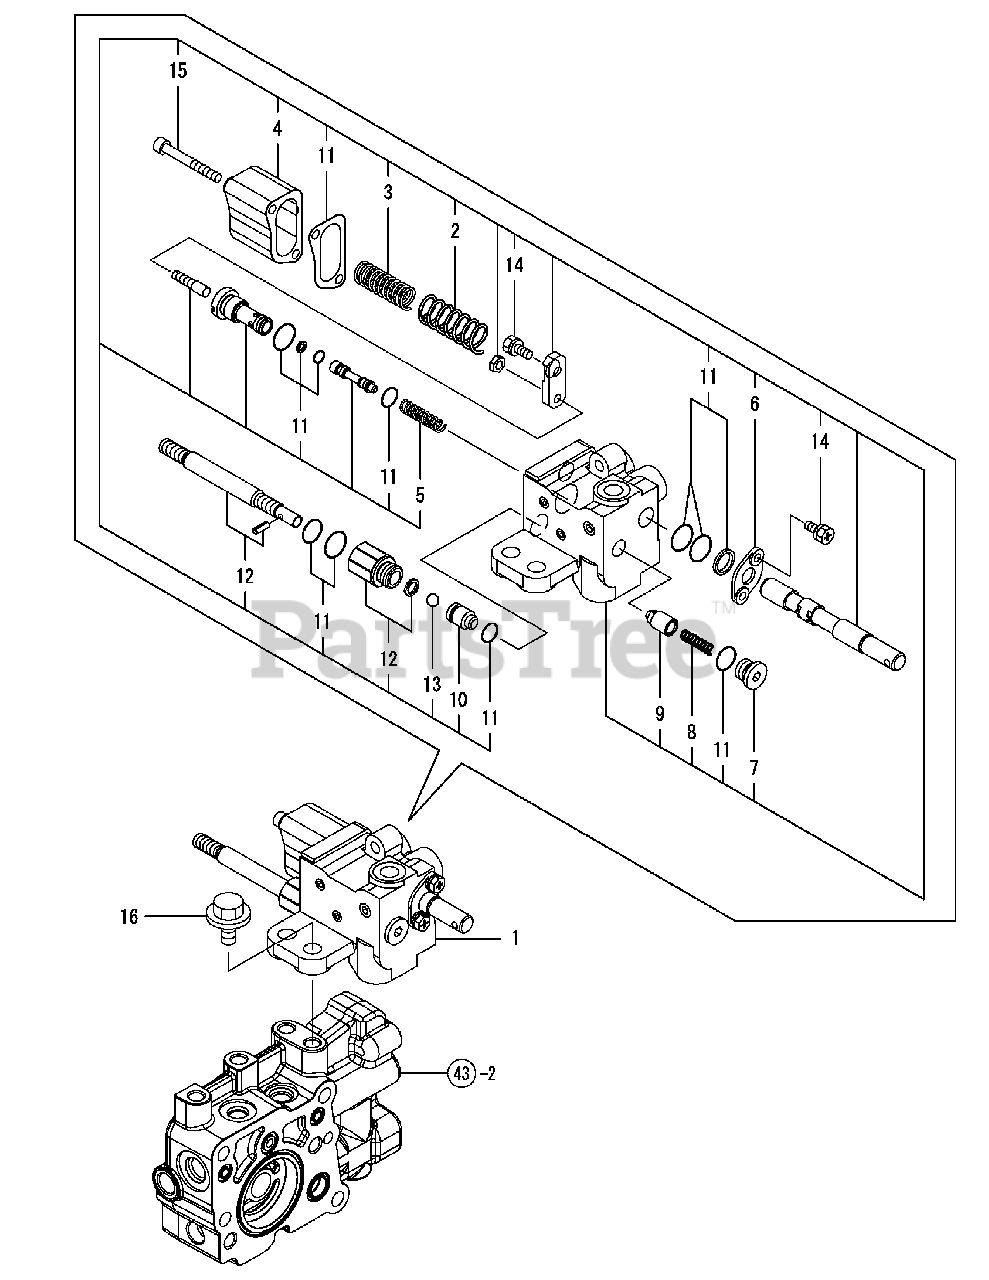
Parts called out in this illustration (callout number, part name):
1	VALVE ASSY, LIFT
2	SPLING, LIFT VALVE
3	SPLING, LIFT VALVE
4	COVER, LIFT VALVE
5	SPRING, MECHA, VALVE
6	PLATE, LIFT VALVE
7	PLUG, LIFT VALVE
8	SPRING, LIFT VALVE
9	POPPET, CHECK, VALVE
10	PLUNGER, LIFT VALVE
11	SEAL KIT, LIFT VALVE
12	STOP BOLT KIT, VALVE
13	BALL 5/16, STEEL
16	BOLT M10X 25 PLATED
